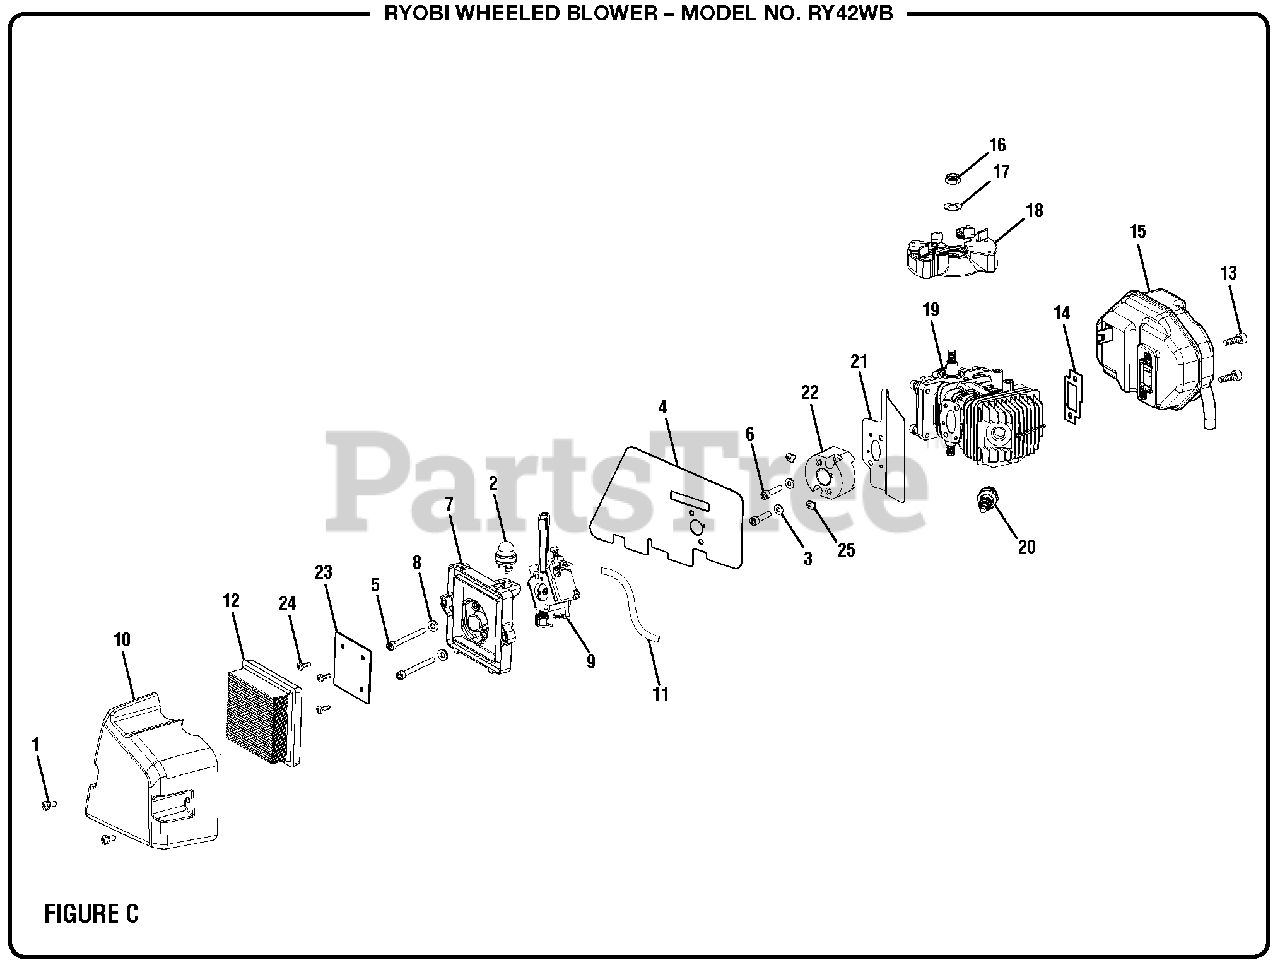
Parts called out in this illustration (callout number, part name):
2	Primer Assembly
3	Spring Washer (M5)
5	Screw (M5 x 50 mm, Soc. Hd.)
6	Screw (M5 x 0.8 in.)
7	Air Box Base
8	Washer (ID5.8 x OD11.5 x 1.7t)
9	Carburetor
10	Air Box Cover
11	Fuel Line
12	Air Filter
13	Bolt (1/4-20 x 18 mm)
15	Exhaust Assembly
16	Lock Nut (M8)
17	Washer (ID9 x OD17.7 x 1.1t)
18	Flywheel Assembly
19	Short Block Assembly
20	Spark Plug (RCJ4)
24	Screw (M4 x 12 mm, Pan Hd.)
25	Washer (Heat Dam)
